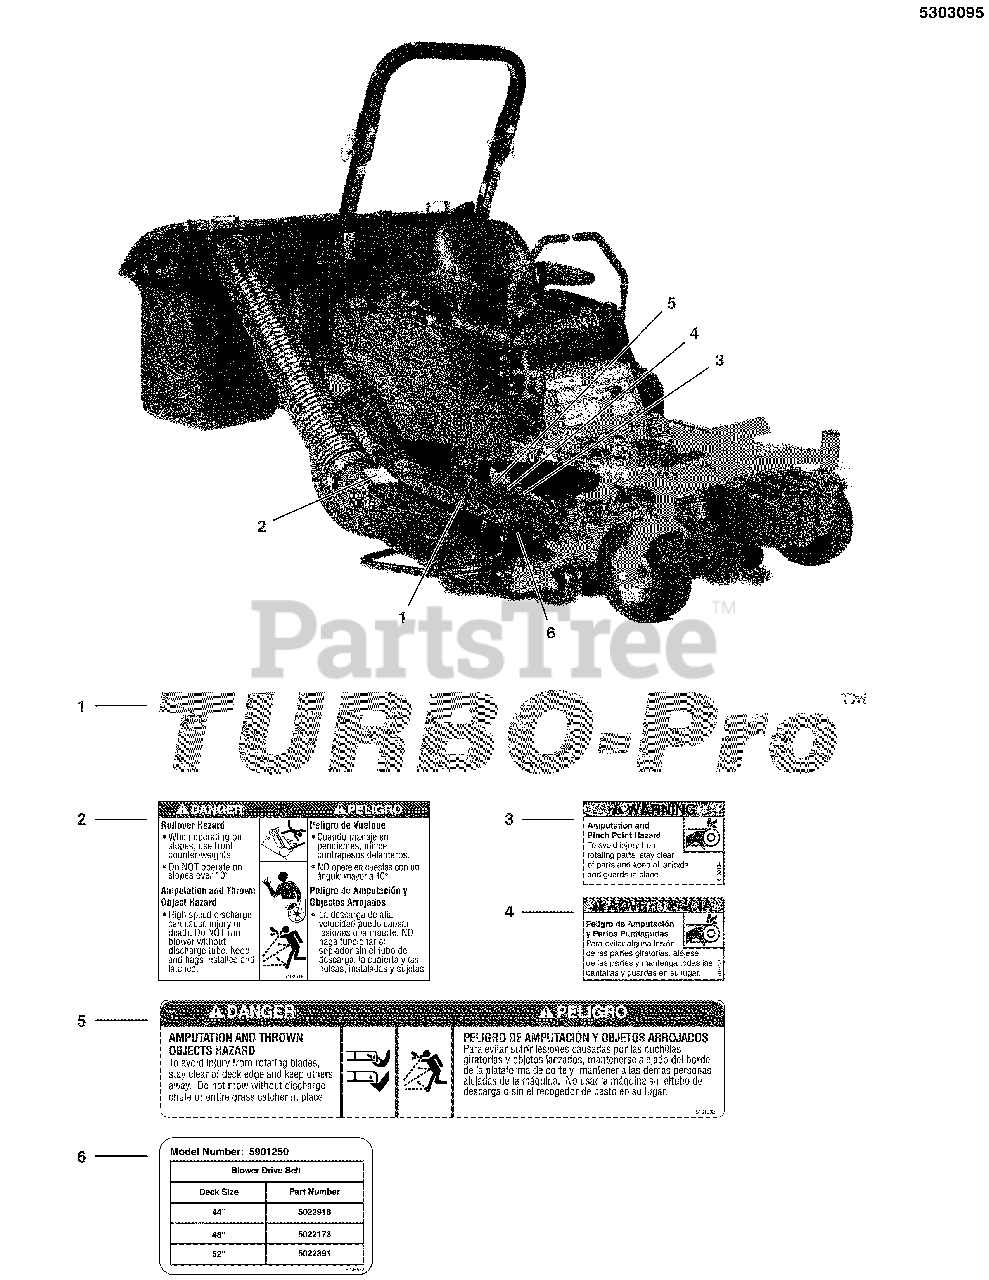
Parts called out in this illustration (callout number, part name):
1	DECAL, TURBO-PRO
2	DECAL, DANGER, TURBO-PRO
3	DECAL, WARNING, HAND IN BELT, ENG
4	DECAL, WARNING, HAND IN BELT, SPA
5	DECAL, DANGER, MOWER DISCHARGE
6	DECAL, BELT, TURBO-PRO
